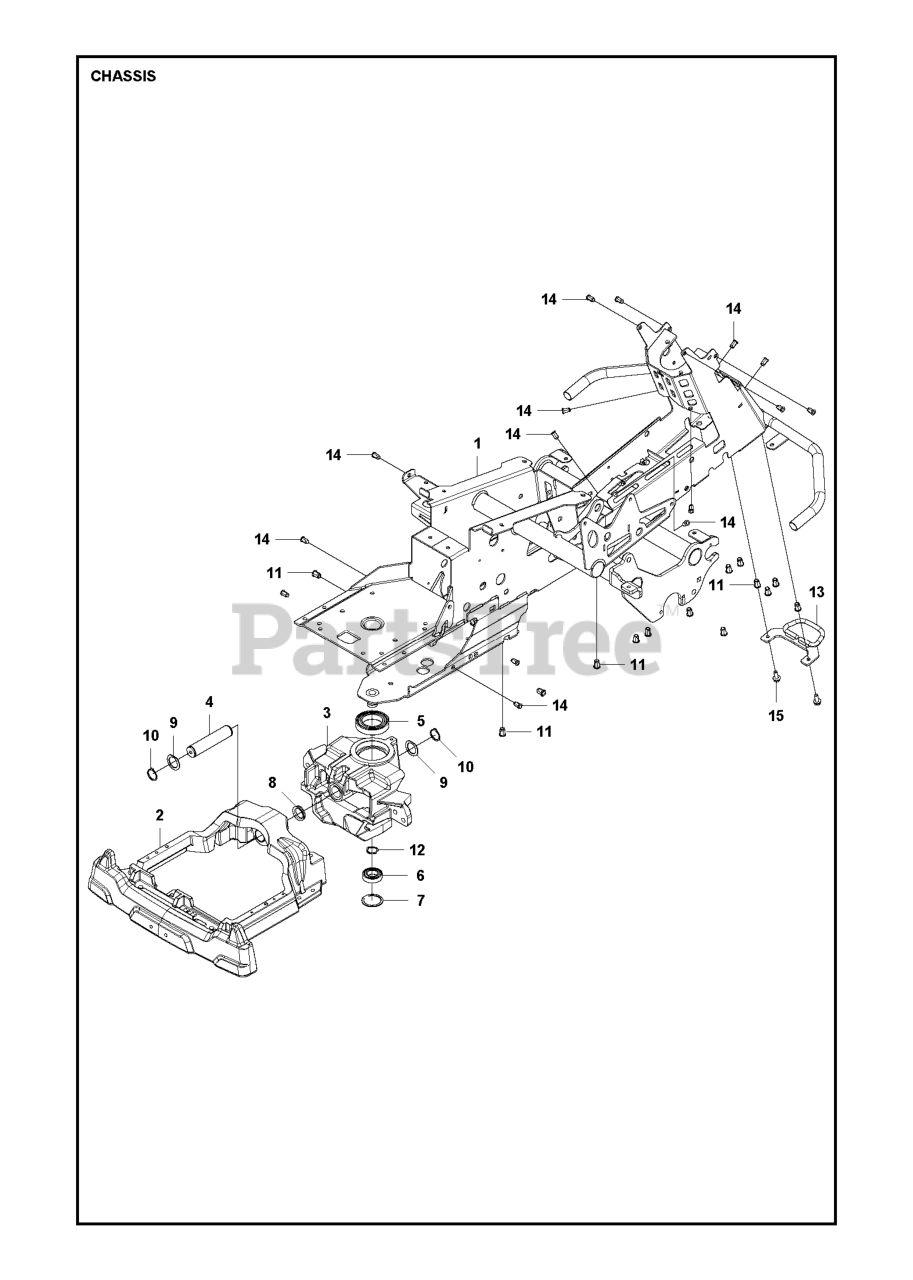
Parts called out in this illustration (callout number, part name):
5	BALL BEARING 6010 2RS1
6	Ball Bearing 6005-2rs
7	CIRCLIP SGH 47
10	Retaining Ring
12	RETAINING RING SGA 25
